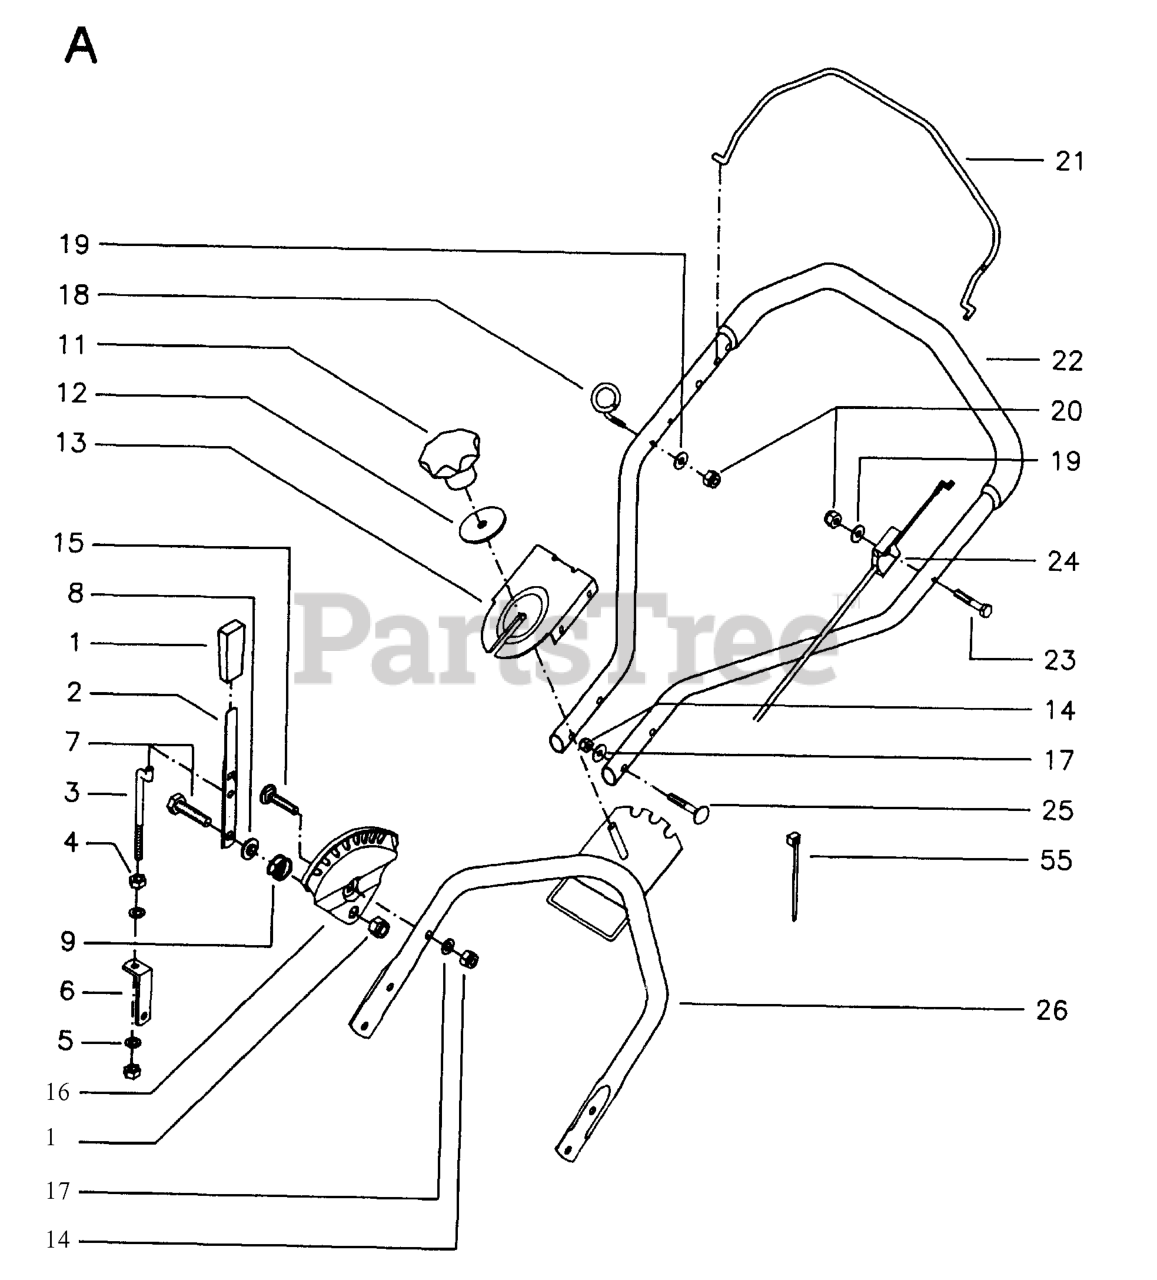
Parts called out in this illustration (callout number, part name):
2	CLUTCH ARM
4	NUT
5	STAR WASHER
9	PRESSURE SPRING
14	LOCKNUT M8
16	INDEXPLATE
17	WASHER - 15X7.3X1.6
18	CABLE GUIDE
20	LOCKNUT M6
23	BOLT FLANGE
